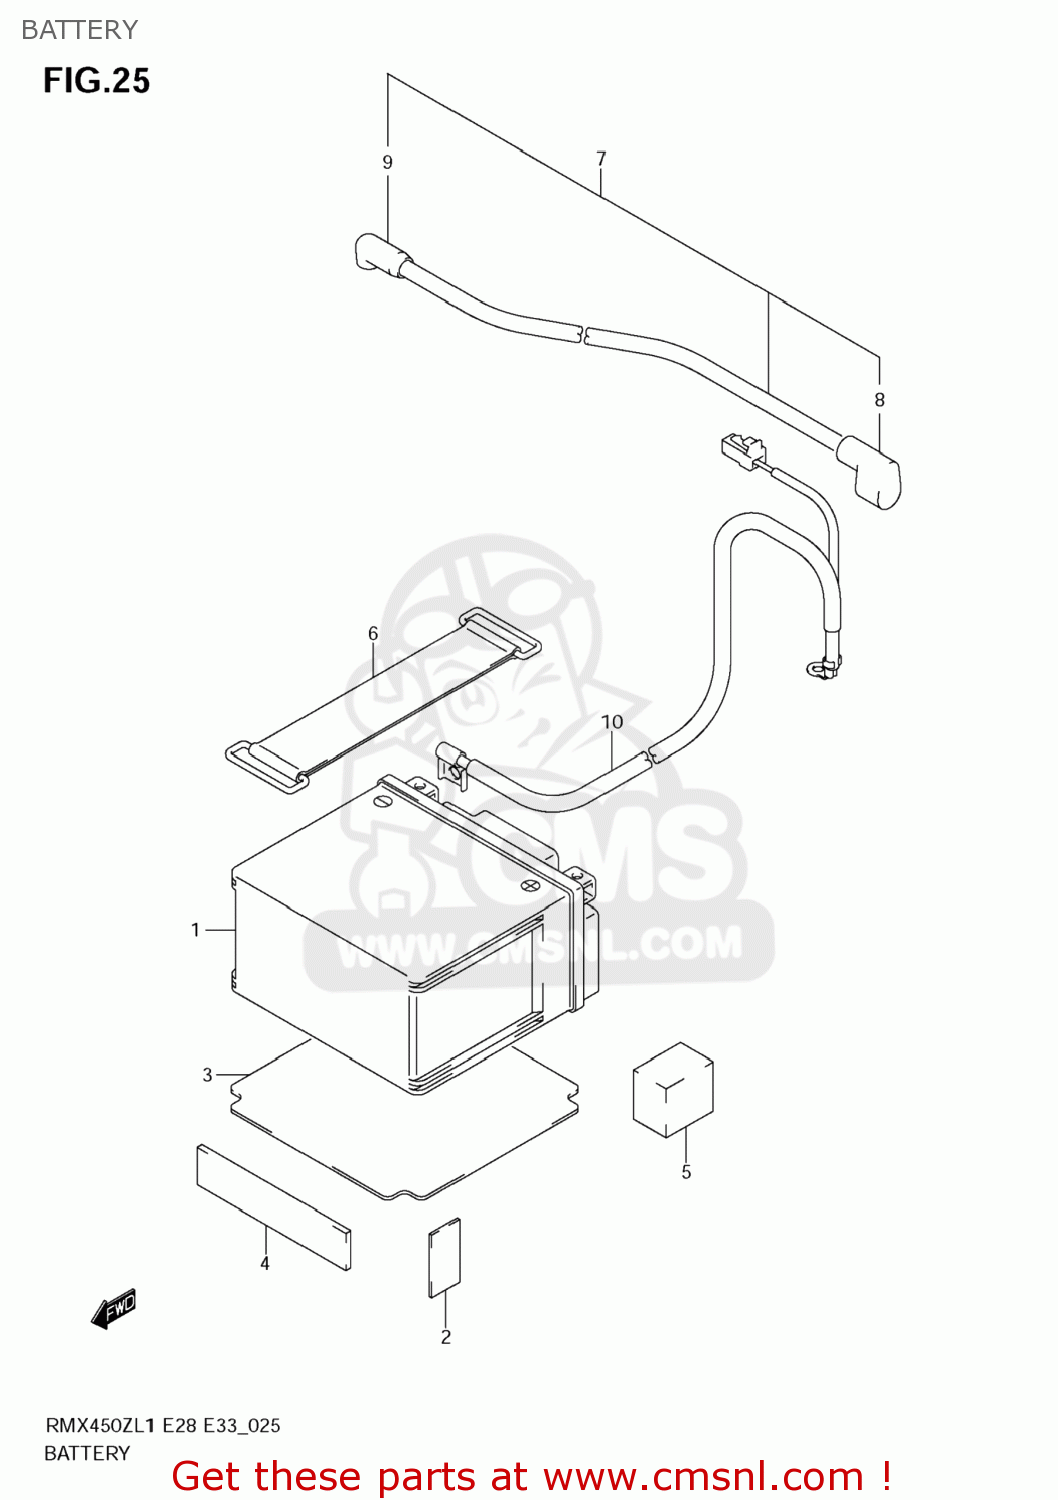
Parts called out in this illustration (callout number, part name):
1	BATTERY ASSY(ELCTLT FILLED)
2	PROTECTOR,BATTERY
3	PROTECTOR,BATTERY NO.2
4	PROTECTOR,BATTERY
5	PROTECTOR,BATTERY
6	BAND
7	WIRE,STARTER MOTOR LEAD
8	CAP,STARTER RELAY
9	CAP,STARTER MOTOR
10	WIRE,BATTERY MINUS LEAD
